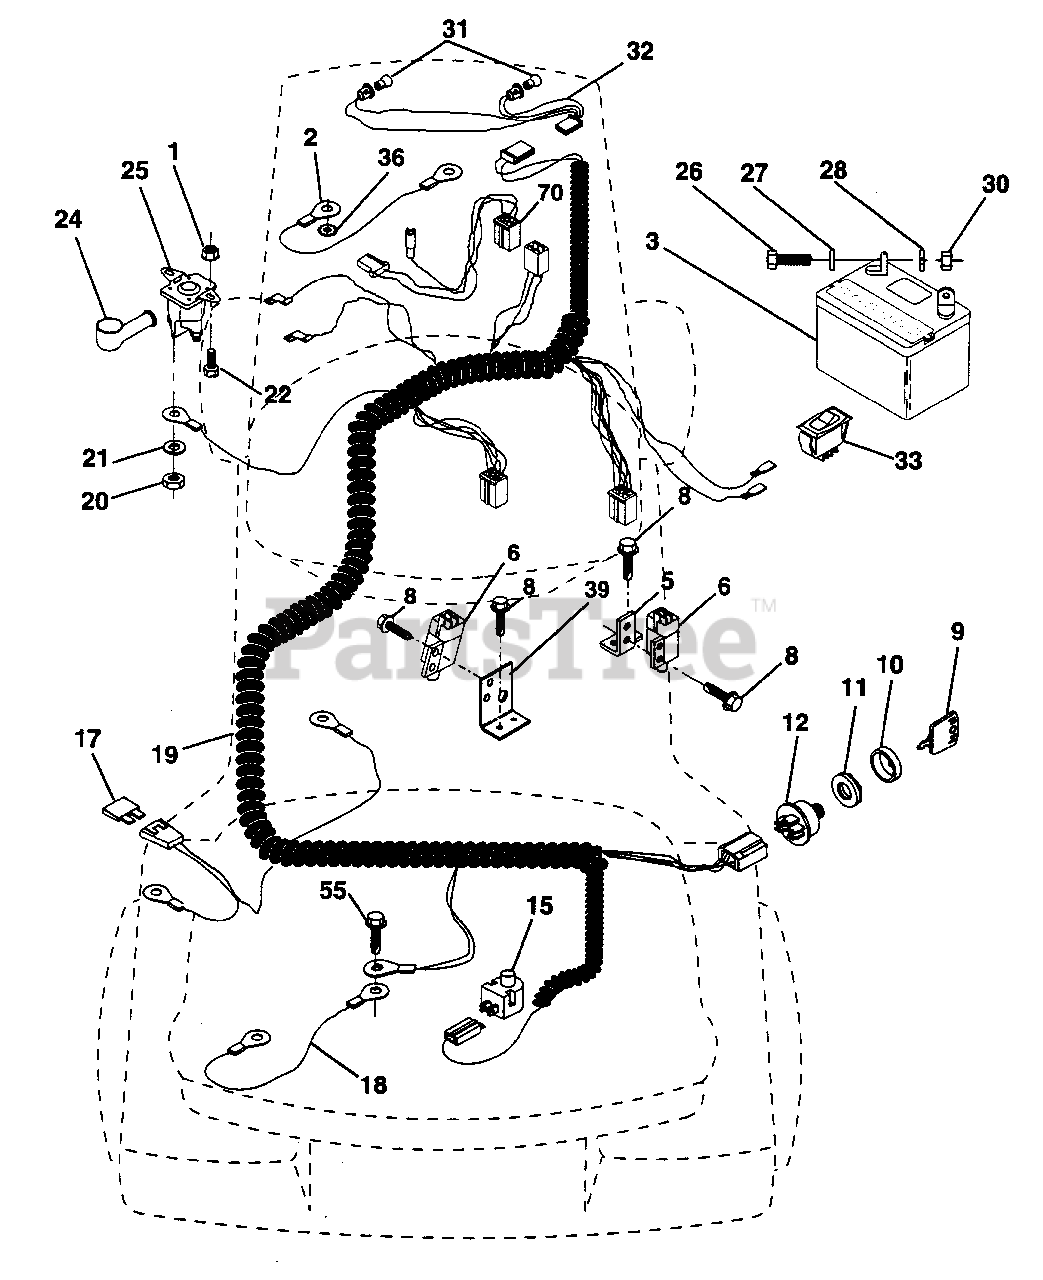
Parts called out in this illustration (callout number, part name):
1	Nut, Hex Keps 1/4-20 (AYP part number)
2	Assembly, Cable (AYP part number)
3	Battery (AYP part number)
5	Bracket, Switch (AYP part number)
6	Switch, Interlock (4-terminal) (AYP part number)
8	Screw, Hex Hd. Tap #10-24 x 1/2 (AYP part number)
9	Key, Molded (AYP part number)
10	Cover, Key Ignition (AYP part number)
11	Nut, Ignition (AYP part number)
12	Switch, Ignition (AYP part number)
15	Switch, Plunger (AYP part number)
17	Fuse (AYP part number)
18	Assembly, Cable (AYP part number)
19	Harness, Ignition (AYP part number)
20	Nut, Hex Jam 1/4-20 (AYP part number)
21	Washer, Lock 1/4 (AYP part number)
22	Bolt, Fin. Hex 1/4-20 UNC x 1/2 Gr. 5 (AYP part number)
24	Cover, Terminal (AYP part number)
25	Solenoid (AYP part number)
26	Bolt, Hex Hd. 1/4-20 UNC x 3/4 (AYP part number)
27	Washer 9/32 x 5/8 x 16 (AYP part number)
28	Washer, Lock 1/4 (AYP part number)
30	Nut, Fin. Hex 1/4-20 UNC (AYP part number)
31	Bulb, Light (AYP part number)
32	Harness, Headlight (AYP part number)
33	Switch, Light (AYP part number)
35	Washer, Lock 5/16 (AYP part number)
36	Washer Lock Inter. Tooth 1/4 (AYP part number)
39	Bracket Switch Clutch (AYP part number)
55	Screw, Thdrol. 5/16-18 x 1/2 (AYP part number)
70	Harness Engine (AYP part number)
